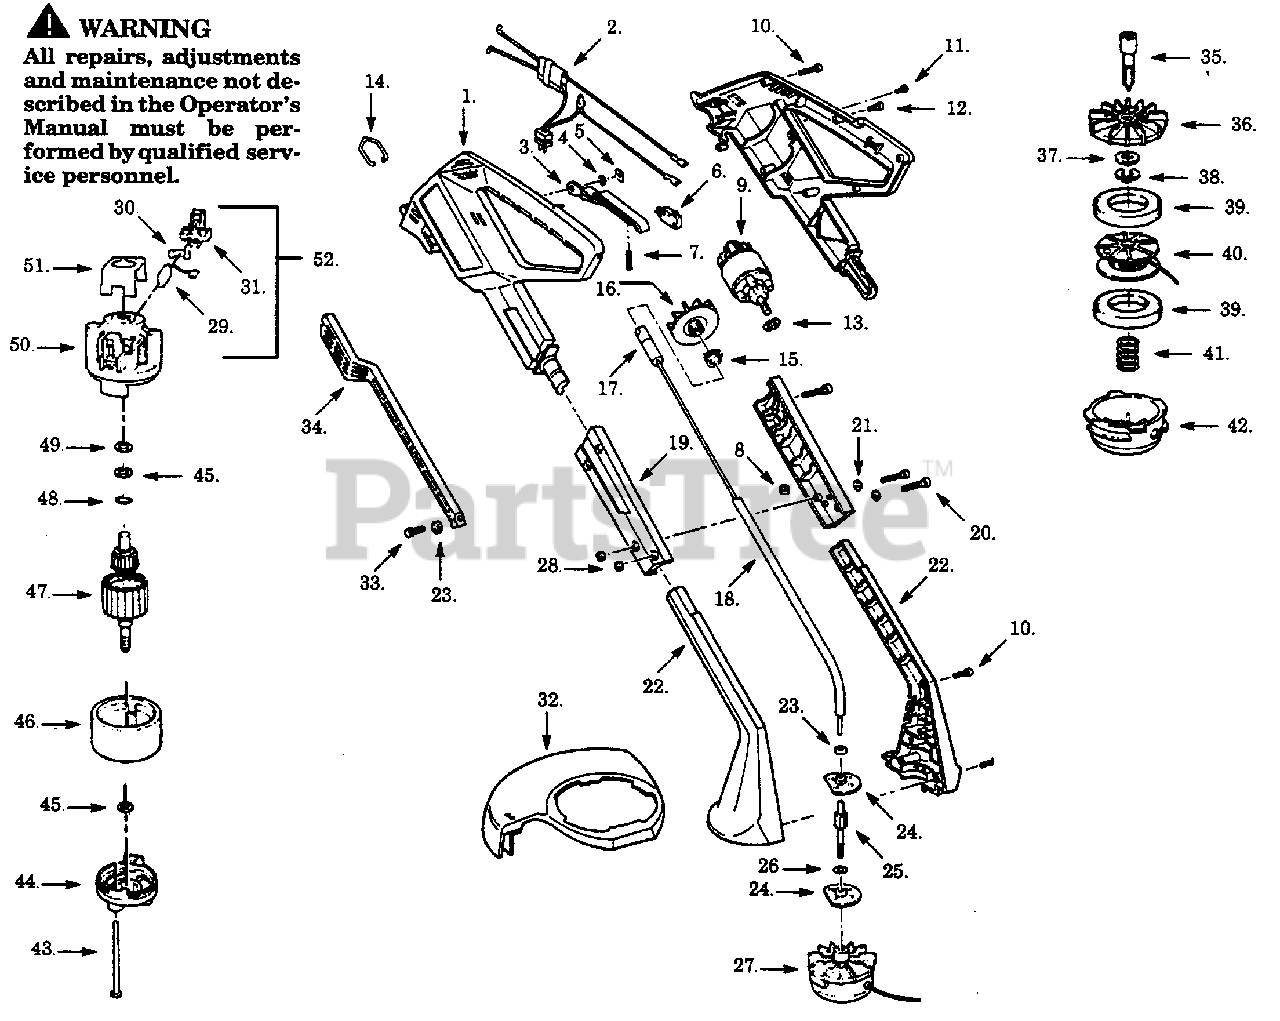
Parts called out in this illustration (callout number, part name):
1	Motor Hsg. Set
5	Push Nut
7	Trigger Spring
8	Square Nut
9	Motor Ass'y.
13	Washer-Thrust
15	Fan Clamp
17	Flex Shaft Ass'y.
18	Sleeve Tubing
19	Housing Clamp
22	Spindle Housing
24	Bearing Holder Disk
25	Shaft Adapter
27	Cutting Head Ass'y.
30	Brush Spring
31	Brush Holder
32	Guard Ass'y.
34	Assist Handle
35	Drive Adapter
36	Rear Plate
38	Retaining Ring
39	Foam Pad
40	Spool & Line
42	Hub Ass'y.
44	Endbell Ass'y. (Drive)
46	Field Ass'y.
47	Armature Ass'y.
48	Retaining Ring
50	Endbell Ass'y. (Brush)
51	Insulator
52	Brush Kit (Incl. 29,30,31)
